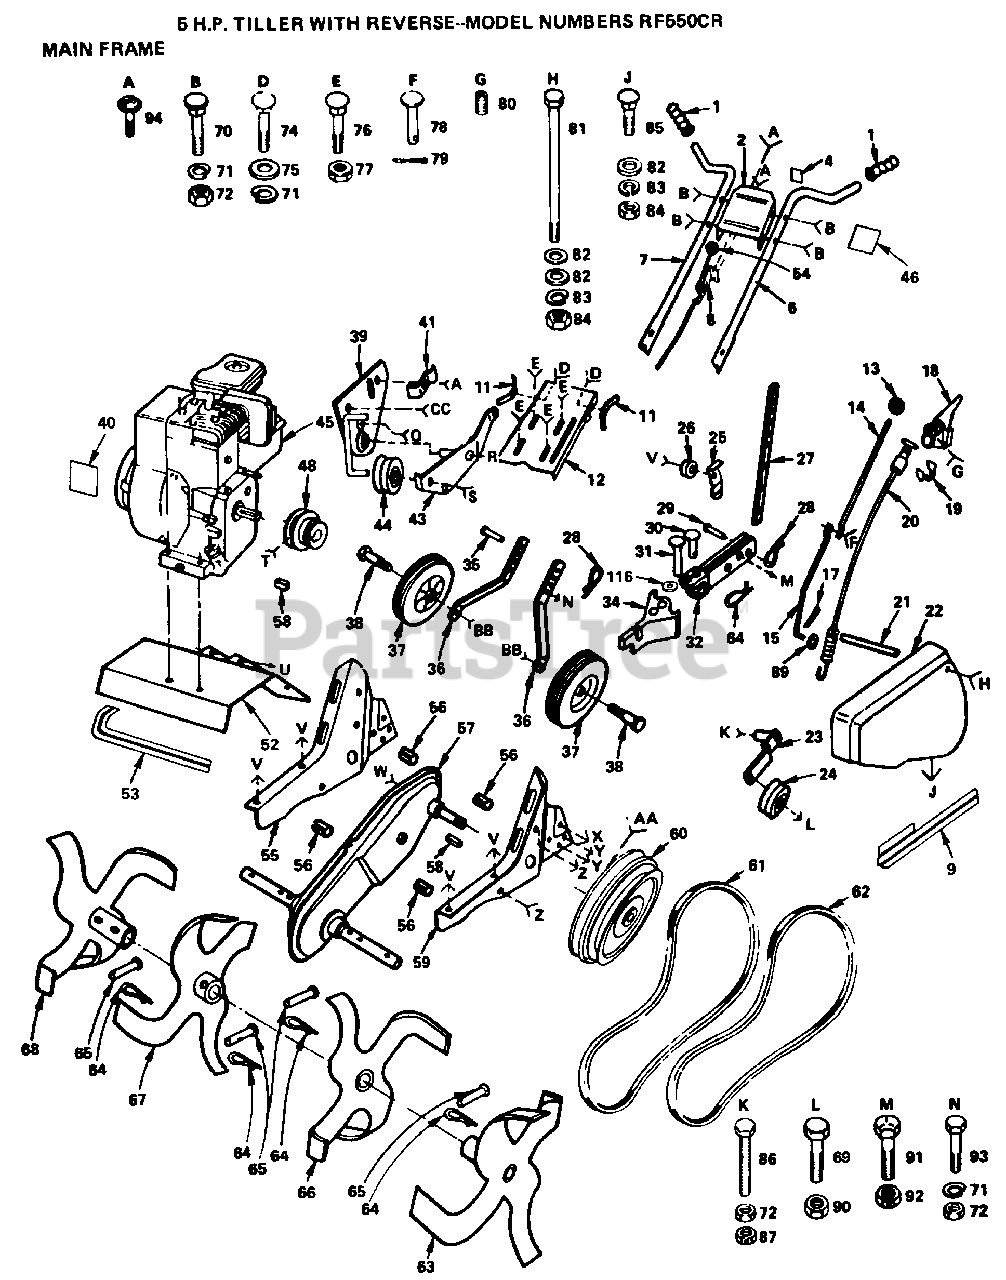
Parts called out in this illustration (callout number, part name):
2	BRACKET - HANDLE
4	DECAL - THROTTLE
4	DECAL, THROTTLE
8	THROTTLE CONT TI
9	DECAL - BELT GUARD
14	ROD REVERSE TI
15	REVERSE ROD TI
17	COTTER PIN
18	CONTROL LEVER TI
19	E-RING
20	CABLE CLUTCH T
21	SPLIT SPACER
23	IDLER ARM TI
25	STAKE SPRING TI
28	SPRING.RETAINER
31	RIVET
32	STAKE HOLDER TI
34	STAKE PIVOT TI
35	DRILLED RIVET RT
37	WHEEL TI
38	BOLT M
41	CONDIUT CLIP T
44	PULLEY W/SPACER
46	DECAL - HANDLE BRACKET
48	ENGINE PULLEY TI
53	DECAL - TINE SHIELD
56	SPLIT SPACER RT
58	KEY T
59	ENGINE BRKT LH TI
63	TINE WELDMENT TI
64	RETAINER.SPRING
65	RIVET.PAN HD.1.75
66	TINE TI
67	TINE TI
68	TINE WELDMENT TI
71	LOCKWASHER
72	NUT.HEX.5/16-18
74	BOLT
75	WASHER
77	NUT
78	RIVET.RD.HD.DRILL
80	SCREW
82	WASHER
83	LOCKWASHER
89	WASHER
90	NUT
92	GRIPCO NUT
94	SCREW TI
